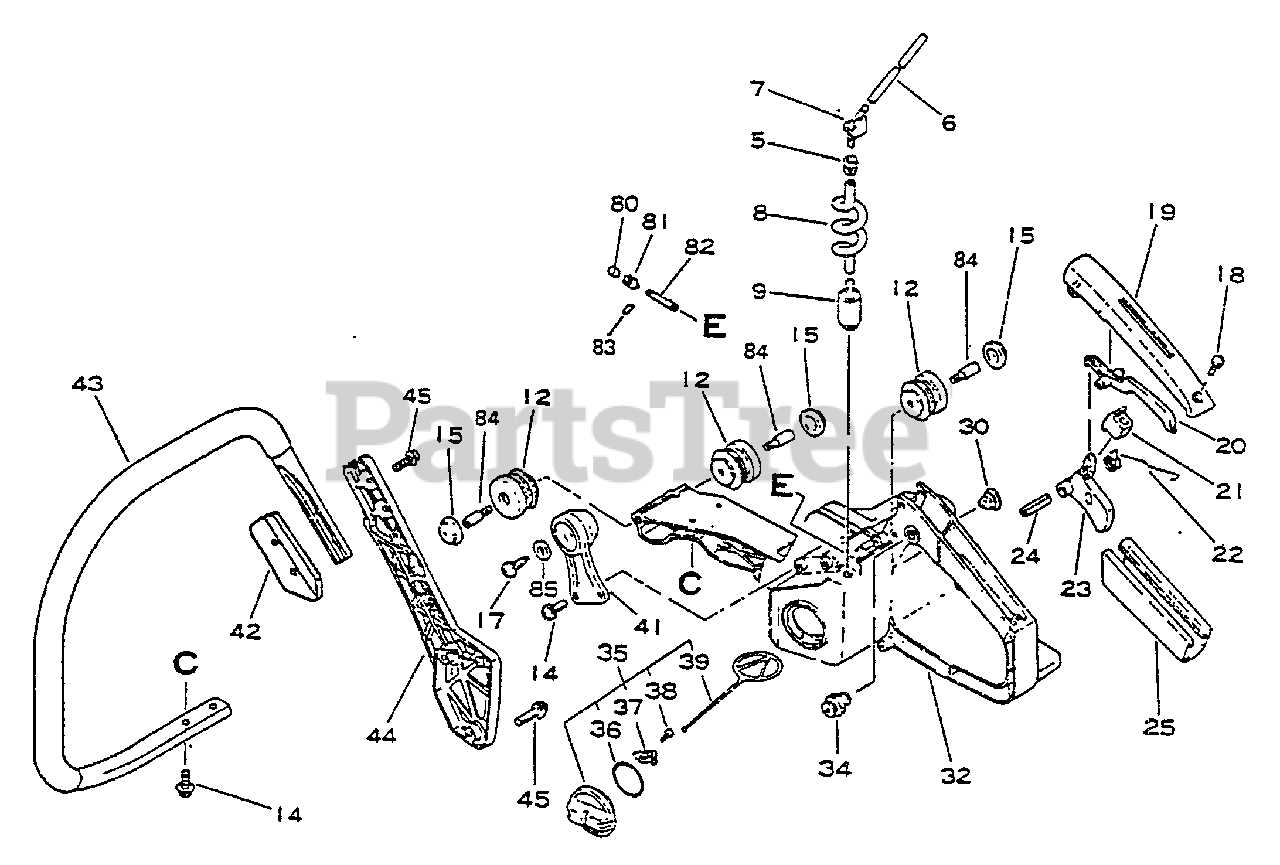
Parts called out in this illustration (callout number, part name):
5	GROMMET
6	PIPE, FUEL - 3×6×100
7	CONNECTOR, PIPE
8	PIPE, FUEL
9	FILTER, FUEL
13	CUSHION
14	BOLT 5×14
15	CAP, CUSHION
18	SCREW 4×14
19	COVER, HANDLE
20	LEVER, THROTTLE LOCKOUT
21	CUSHION, THROTTLE
22	SPRING, THROTTLE RETURN
23	TRIGGER, THROTTLE - ORANGE
24	PIN, SPRING
32	HANDLE - REAR
34	LOCK, THROTTLE
35	CAP ASSY
36	O-RING 29
37	RETAINER, CONNECTOR
38	SCREW, TAPPING 3×8
39	CONNECTOR, CAP L= 60 MM
42	BRACKET, HANDLE
43	HANDLE, FRONT
44	BRACKET, GRAY HANDLE
45	SCREW 5×20
80	VENT ASSY
81	HOLDER, VENT
82	PIPE, VENT
85	WASHER, FLAT 5.5×10×0.8
